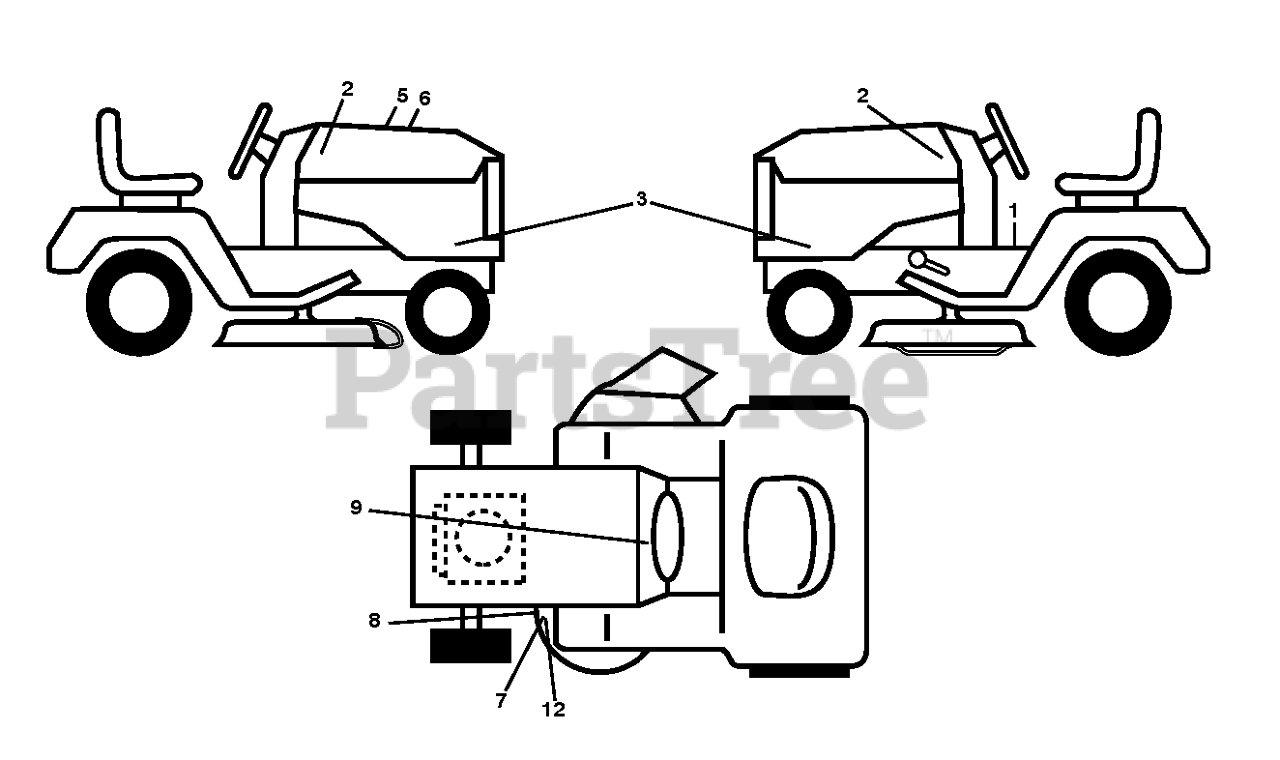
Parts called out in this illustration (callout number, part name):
1	DECAL.FENDER.WARNING
2	RP.DECAL.BADGE.170MM.TEXTLOGO
3	DECAL.SDPNL.YTH26V54.HUSQ.X668
5	DECAL.WARNING.CUST.RESP.E85.
6	DECAL.RPL.BSM44.PROF.TLW.54K46
7	DECAL.WARN.KEEP.HAND.AWAY
8	DECAL.MOWER
9	DECAL BTRY SYMBOLS
12	DECAL.MOWER.SCH.48/54
